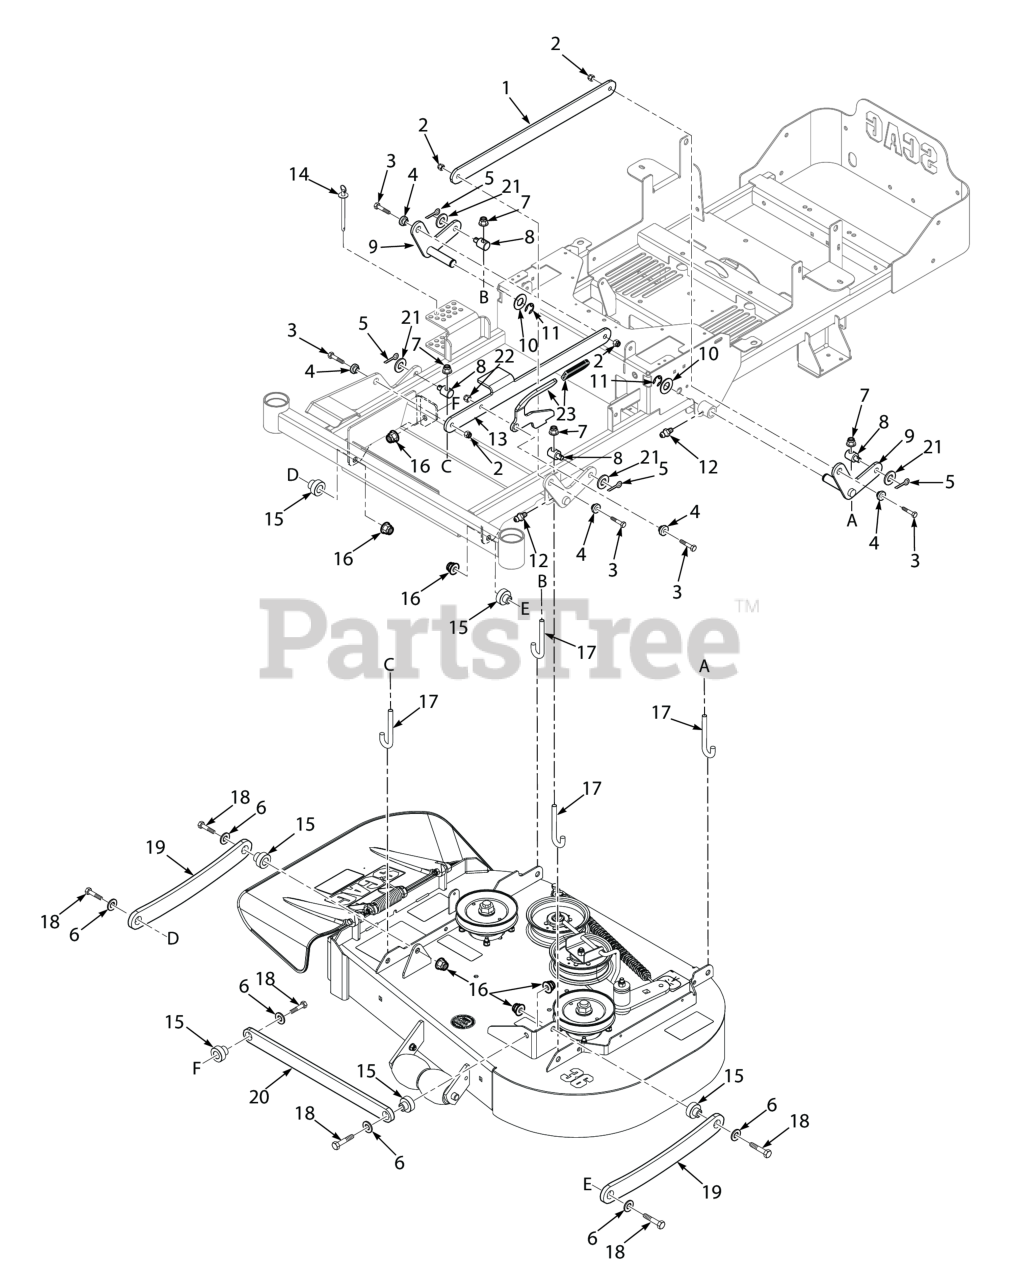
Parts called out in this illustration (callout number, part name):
1	Link, Deck Lift - LH
2	Nut, Flange Elastic Stop Nut, 3/8-16
3	Bolt, Hex Head 3/8-16 x 1-1/4", Kawasaki FX / FT & FT-EFI
4	BUSHING, SPEED ADJUSTMENT LEVER
5	Pin, Cotter 3/16 x 1.0"
6	Flatwasher, 1/2 - .531 x 1.062 x .095
7	HEX LOCKNUT, ELASTIC STOP, 1/2-13
8	Joint, Swivel
9	Lift Bellcrank Weldment
10	Flatwasher, 3/4 (.766 x 1.250 x .060)
11	RETAINING RING, 3/4" EXTERNAL "E"
12	GREASE FITTING, STR. 1/4-28 SELF TAP.
13	Link, Deck Lift - RH
14	Pin Assembly, Deck Height
15	Bushing, Deck Lift
16	Nut, Elastic Stop 1/2-13, (STT-52 & STTII-52)
17	Rod, Deck Lift
18	Bolt, Hex Head 1/2-13 x 1-3/4"
19	Pull Arm, Deck
20	Lateral Link
21	Flatwasher, 5/8" (.656 x 1.312 x .095")
22	HEX NUT, ELASTIC STOP LOCK, 3/8-16
23	Lever Assembly (incl. Grip)
